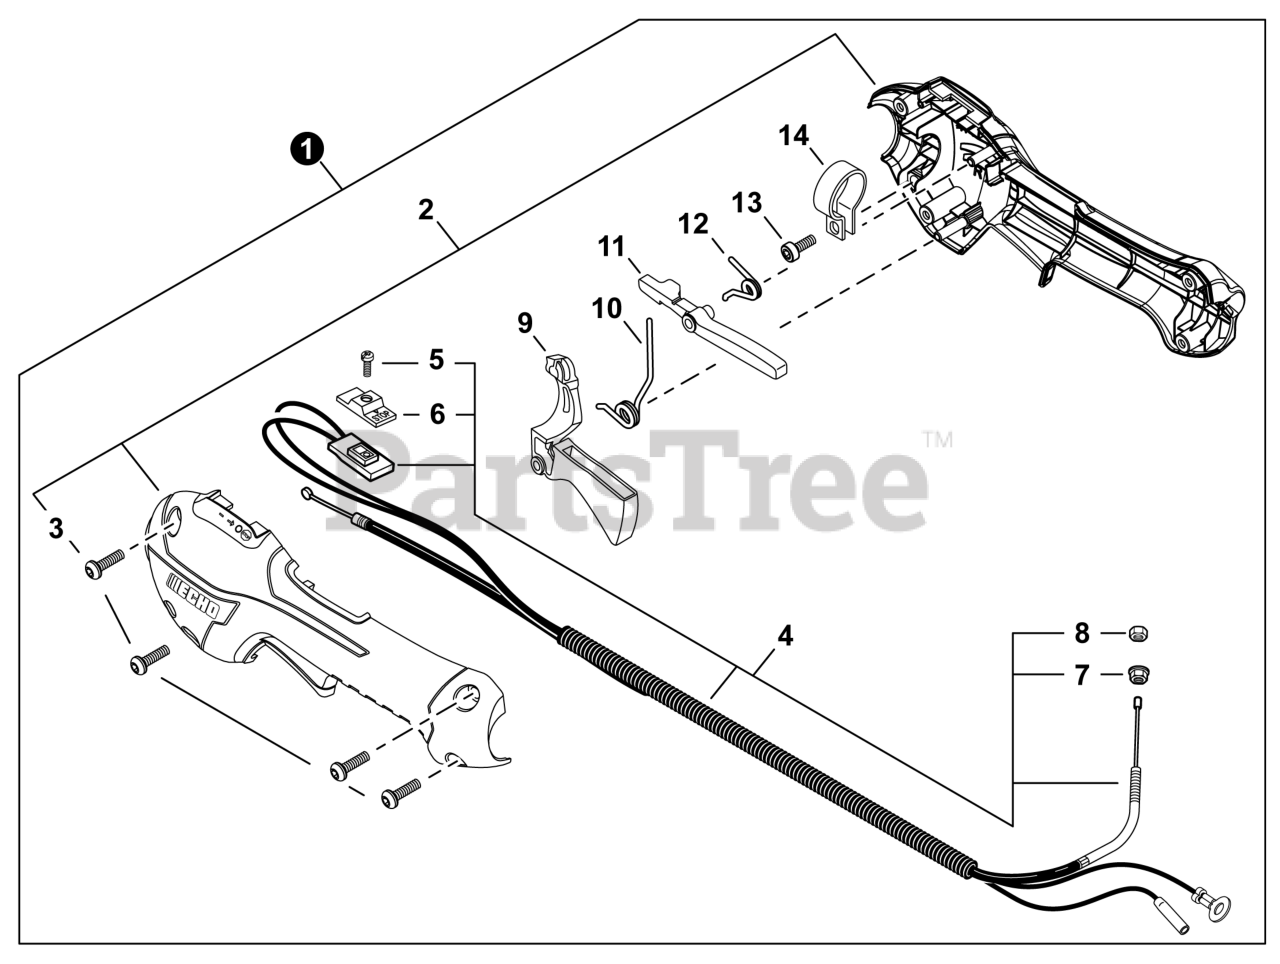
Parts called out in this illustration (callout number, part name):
1	CONTROL HANDLE ASSY
2	CONTROL HANDLE KIT
3	BOLT, TORX 5x16
4	CABLE ASSY, CONTROL
5	SCREW 3x10
6	KNOB, SWITCH - ORANGE
7	NUT, FLANGE M6
8	NUT M6
9	TRIGGER, THROTTLE
10	SPRING, TORSION
11	LEVER, THROTTLE LOCKOUT
12	SPRING, TORSION
13	BOLT, TORX 5x16
14	CLAMP
